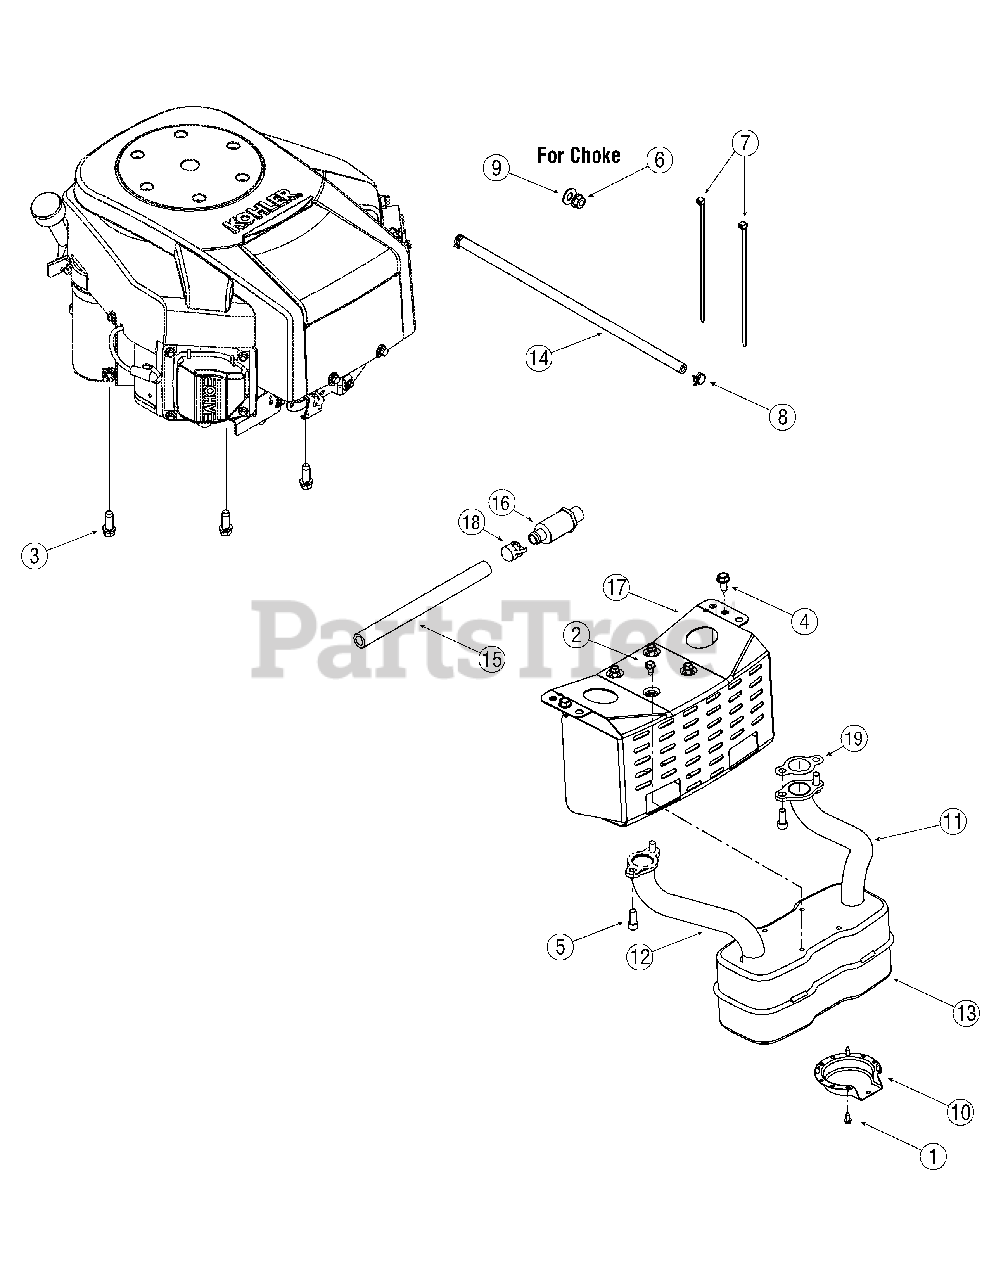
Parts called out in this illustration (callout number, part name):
1	AB Screw #8-18 x 0.5
2	TT Screw 1/4-20 x 0.5
3	TT Screw 3/8-16 x 1.00
4	AB Screw 5/16-12 x 0.5
5	Screw, 5/16-18 x .750
6	Flange Lock Nut, 3/8-16
7	Cable Tie
8	Hose Clamp
9	Flat Washer, .406 x .875 x .059
10	Muffler Deflector
11	LH Exhaust Pipe
12	RH Exhaust Pipe
13	Dual Inlet Muffler
14	Fuel Line Hose
15	OIl Drain Extension Hose
16	Oil Drain Valve
18	Oil Drain Cap
19	Exhaust Gasket
